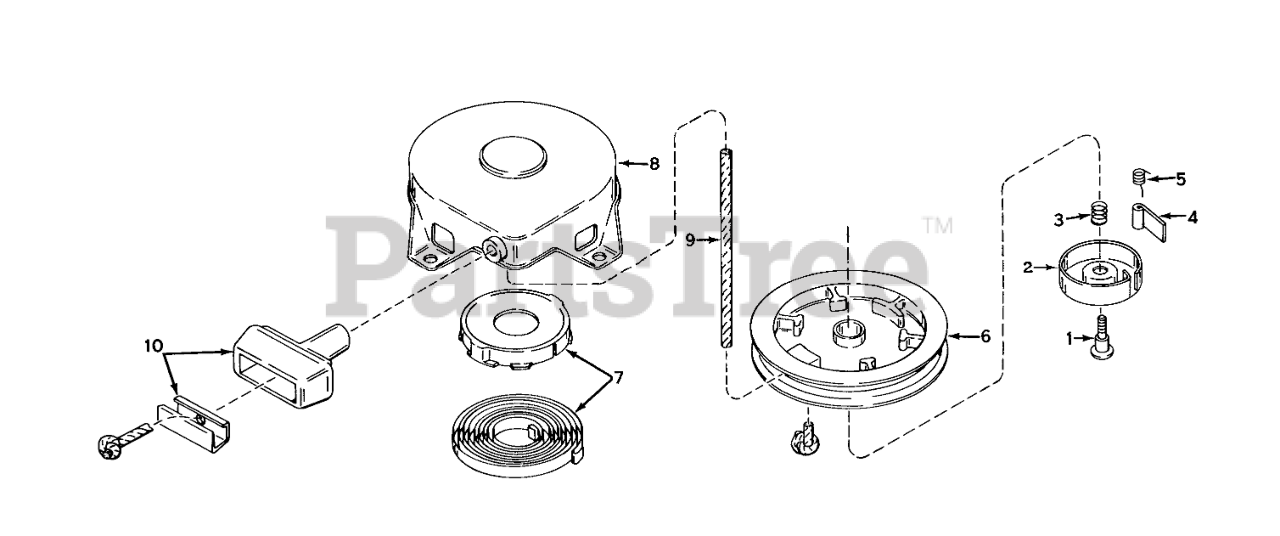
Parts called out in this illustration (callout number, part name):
1	Screw
2	Retainer
3	Spring-Brake
4	Dog-Starter
5	Spring-Dog
6	Pulley
7	Spring & Keeper Assy
8	STARTER HOUSING ASSY
9	Rope Starter
10	Assy., Starter
